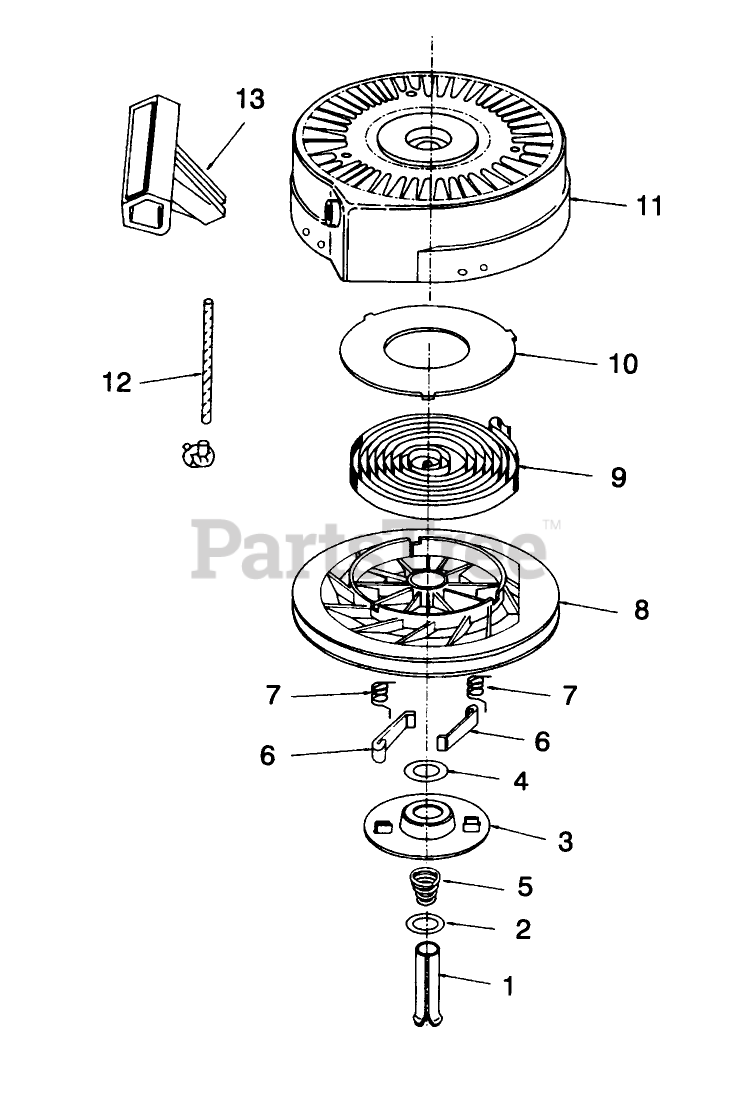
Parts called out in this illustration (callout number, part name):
1	Pin, Spring (Incl. Ref. #7)
2	Washer
3	Retainer
4	Washer
5	Brake Spring
6	Dog-Starter
7	Spring-Dog
8	Pulley and Rewind Spring ASM
9	Rewind Spring
10	Cover-Spring
11	Starter Housing ASM
12	Rope-Starter (98 cut to length)
13	Handle-Starter
